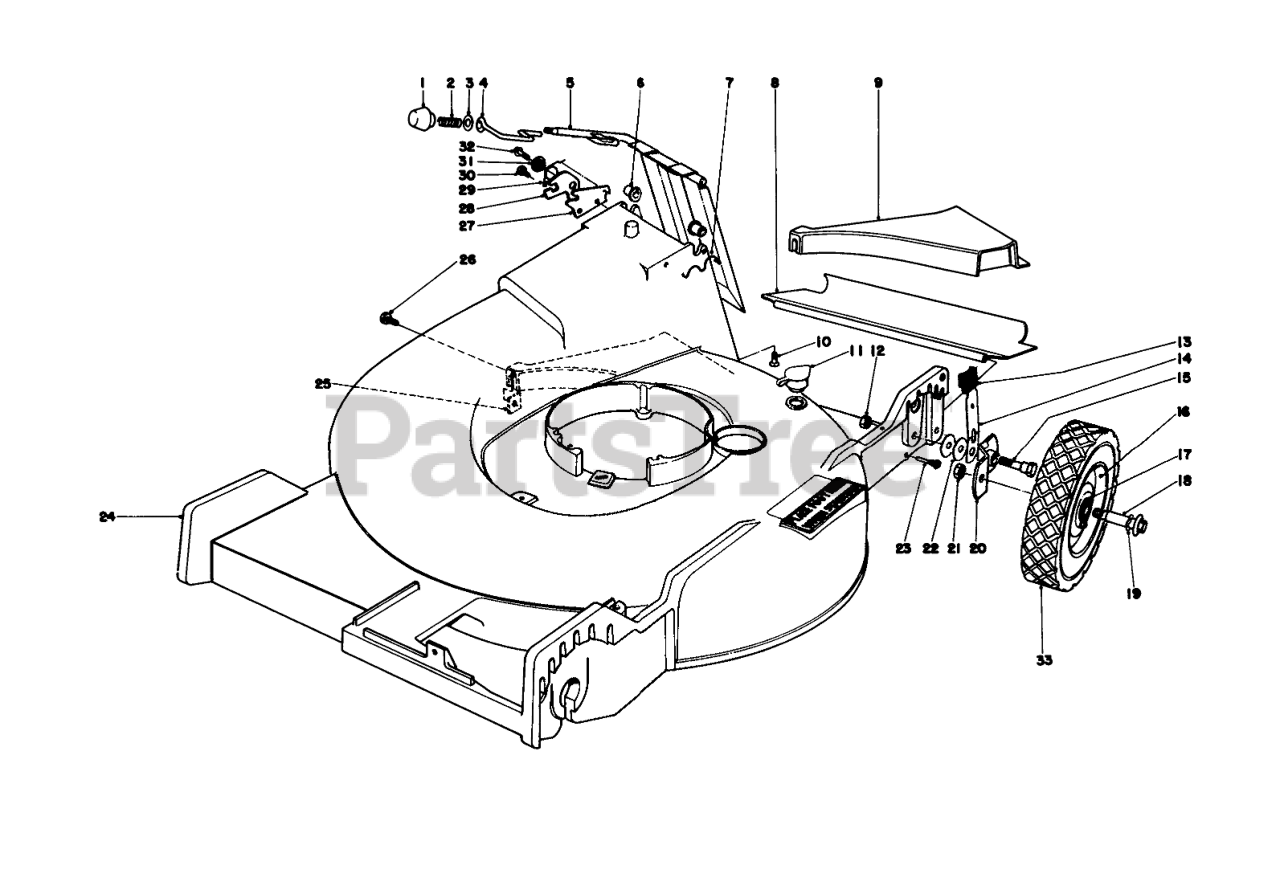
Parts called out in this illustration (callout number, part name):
2	COMPRESSION SPRING
3	WASHER
4	DOOR LATCH
5	Door Handle
6	BUSHING-NYLON
7	Door Retainer
8	REAR SAFETY SHIELD
9	REAR INSERT
10	SCREW-HH
11	WASHOUT PLUG
12	Nut
13	KNOB-ARM
14	SPRING ARM ASM
15	PIVOT SCREW
16	Wheel & Tire Assembly (Incl. Ref. #17 & 33)
17	BEARING-BALL
19	SPRING WASHER
20	PIVOT ARM ASM A
21	Nut
22	WASHER-PIVOT
23	SAFTEY SHIELD SCREW
24	Housing
25	SPECIAL NUT
27	DOOR LATCH PLATE
28	Latch Safety
29	TORSION SPRING
30	SCREW-HWH
31	Latch Spacer
32	Screw
